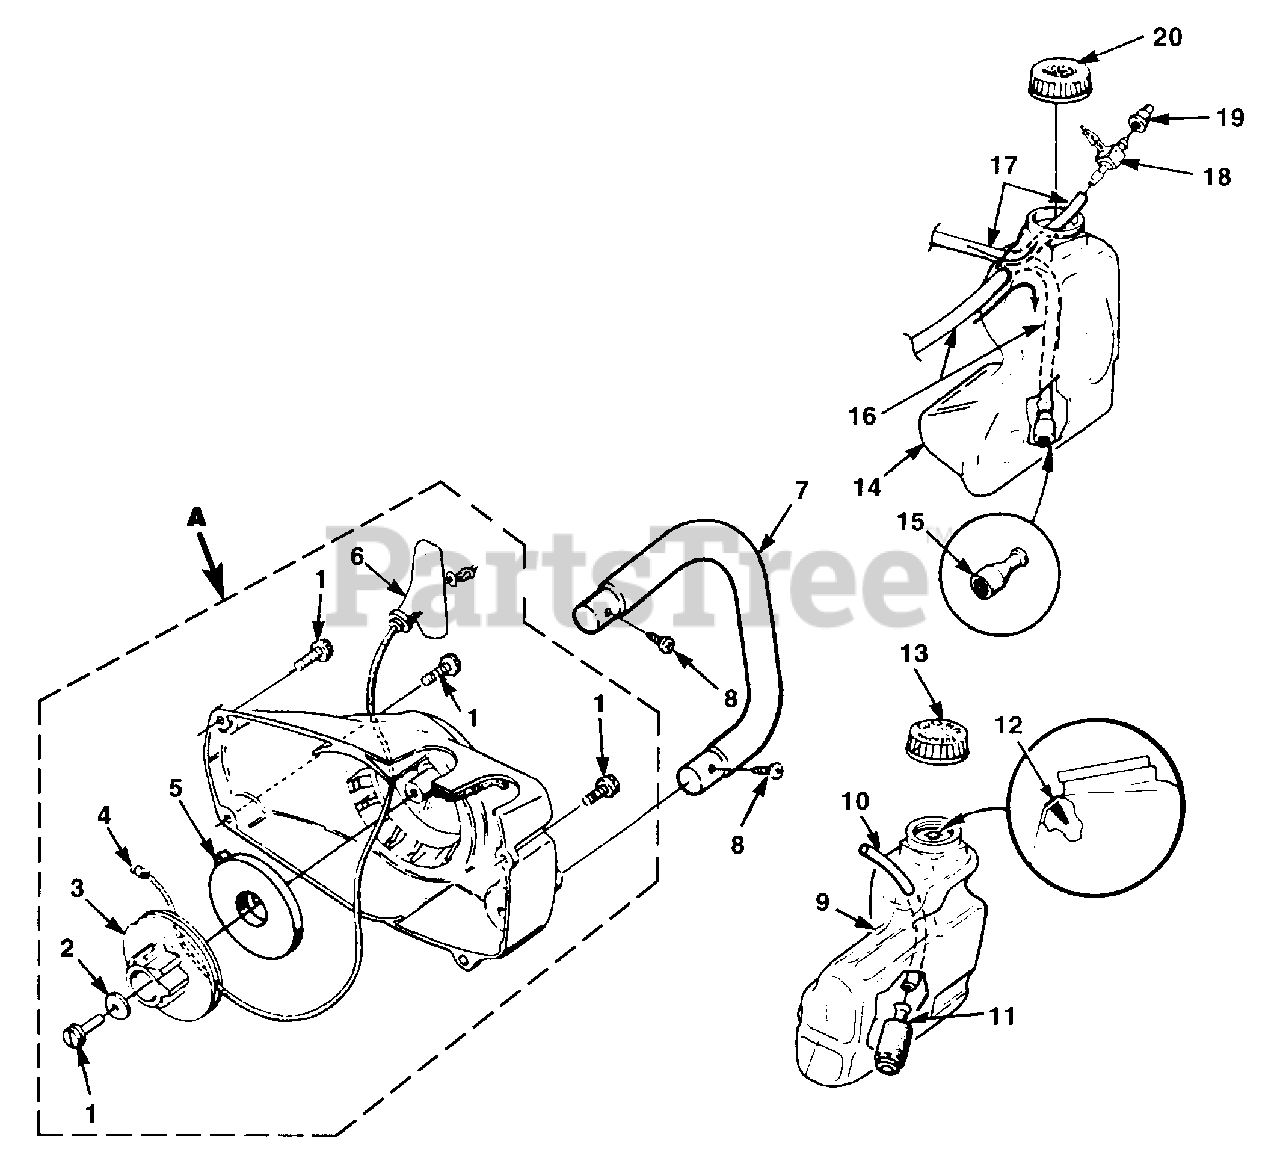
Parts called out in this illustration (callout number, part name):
1	SCREW - Torx (#10 X 3/4")
2	WASHER - Retaining (#10)
3	PULLEY - Starter
4	ROPE - Starter (46")
5	SPRING & CONTAINER
6	GRIP - Starter
7	HANDLE BAR
8	SCREW - Pan Plastite (#10-16 X 3/4")
9	FUEL TANK
10	TUBING - Rubber (7")
11	FILTER - Fuel
12	VALVE - Duck Bill
13	FUELCAP
14	OIL TANK
15	FINDER - Oil
16	TUBING - Rubber (8")
17	TUBING - Rubber (5")
18	FITTING - Vent
19	VALVE - Check
20	OIL CAP
A	STARTER ASSY., Complete
